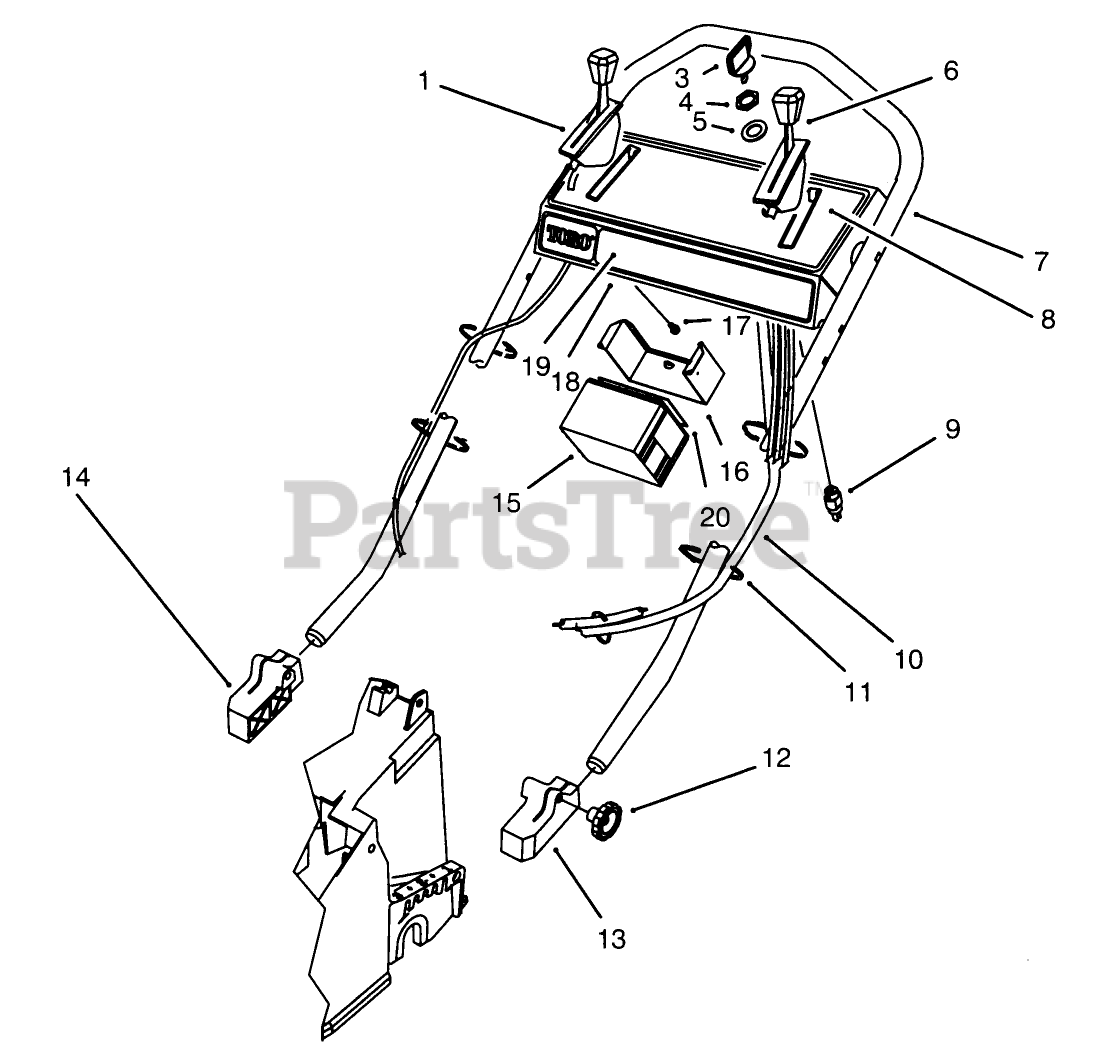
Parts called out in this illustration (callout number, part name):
1	CONTROL-SPEED, GROUND
3	KEY-IGNITION
4	NUT-HH
5	WASHER-LOCK
6	CONTROL - THROTTLE
7	HANDLE - 53CM (DIPPED)
9	STARTER SWITCH ASM
11	TIE-CABLE
13	MOUNT-HANDLE, LH
14	MOUNT-HANDLE, RH
15	BATTERY ASSEMBLY,WET
17	SCREW-TAP
18	PANEL W/DECALS
19	DECAL - PANEL KEY
20	DECAL-BATTERY
